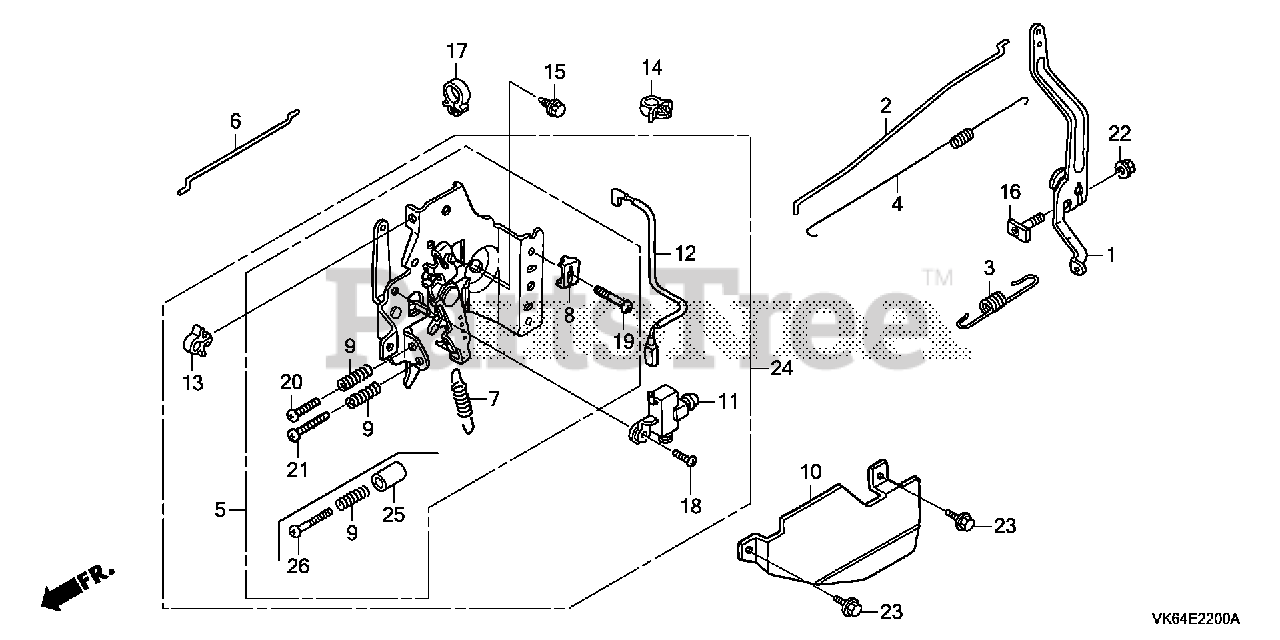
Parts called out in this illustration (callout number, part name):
1	ARM, GOVERNOR
2	ROD, GOVERNOR
3	SPRING, GOVERNOR
4	SPRING, THROTTLE RETURN
6	ROD, CHOKE
7	SPRING, LEVER
8	HOLDER, CABLE
9	SPRING, CONTROL ADJUSTING
10	PROTECTOR, CONTROL
11	SWITCH ASSY., ENGINE STOP
12	WIRE, STOP SWITCH
13	HOLDER, STOP SWITCH WIRE
14	CLAMP, BRAKE PIPE (GRAY)
14	CLAMP, HARNESS
15	BOLT, FLANGE (6X12) (CT200)
16	BOLT, GOVERNOR ARM
17	CLIP, WIRE HARNESS
17	CLIP, HARNESS
18	SCREW, PAN (4X8)
19	SCREW, PAN (5X16)
20	SCREW, PAN (5X20)
22	NUT, FLANGE (6MM)
23	BOLT, FLANGE (6X10)
24	CONTROL ASSY.
25	COLLAR, STOPPER
26	SCREW, RECESSED (5X28)
